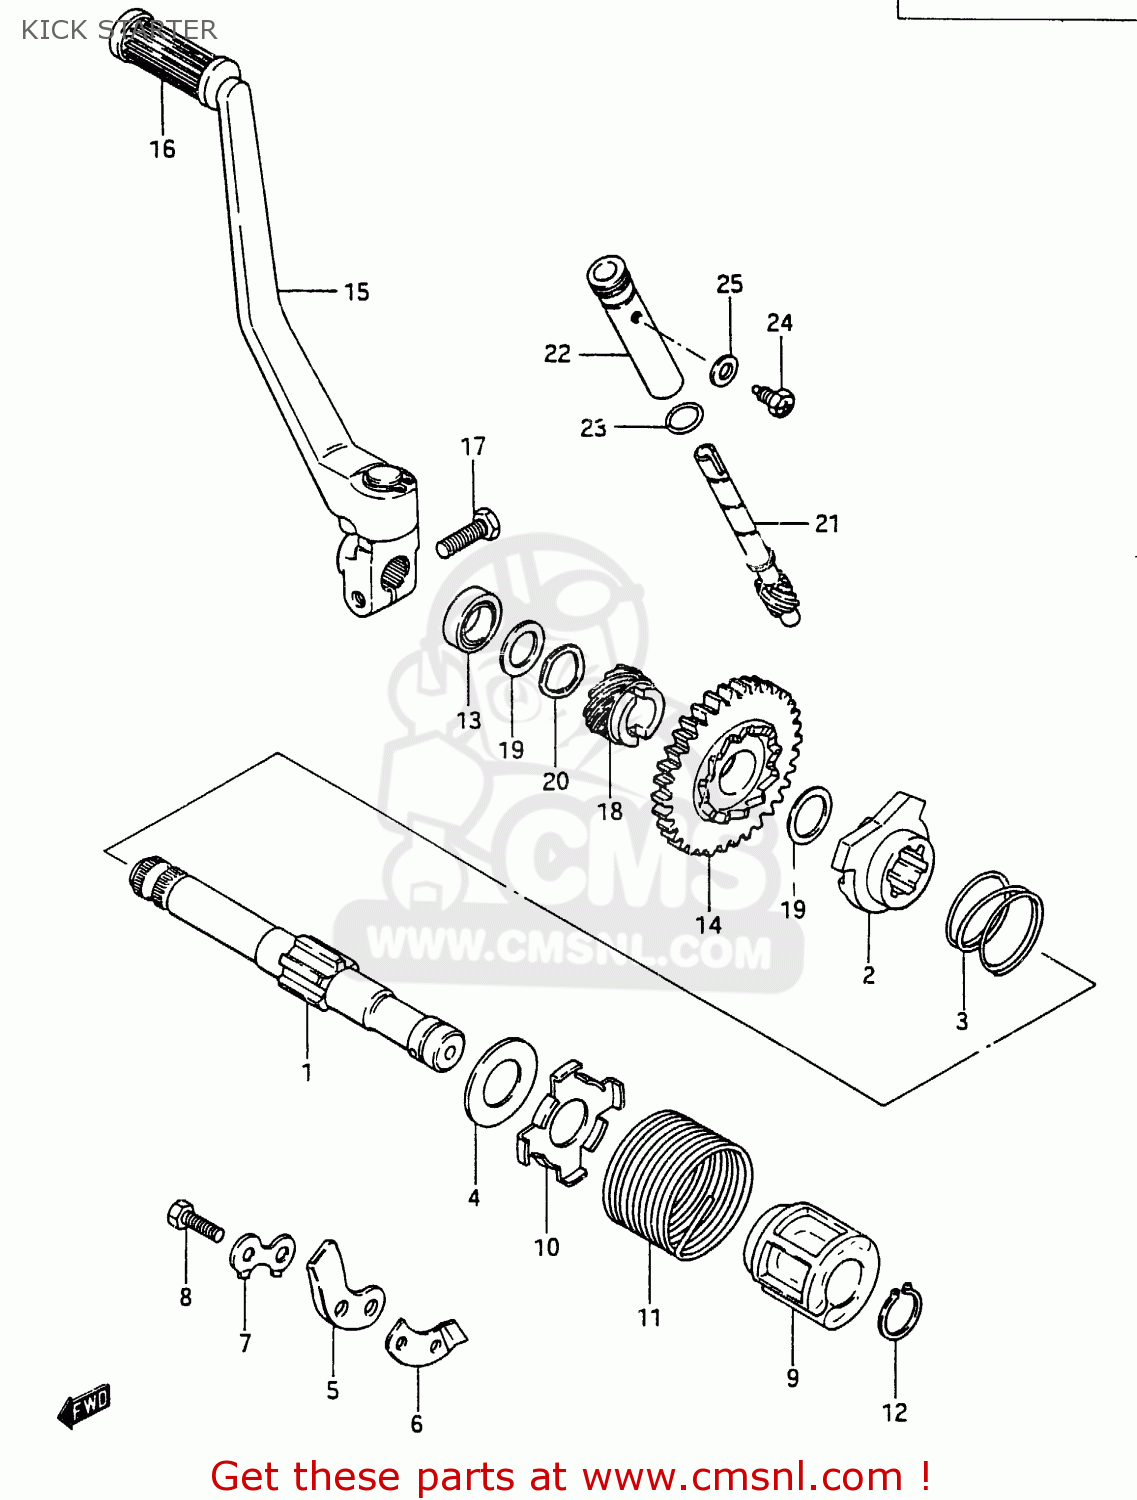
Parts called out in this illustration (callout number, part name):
1	SHAFT, KICK STARTER
2	STARTER, KICK
3	SPRING
4	WASHER
5	GUIDE, KICK STARTER
6	STOPPER,KICK STARTER
7	WASHER
8	BOLT
9	GUIDE,KICK SHAFT SPRING
10	HOLDER,KICK SHAFT SPRING
11	SPRING
12	CIRCLIP
13	SEAL,OIL(16X24X5)
14	GEAR, KICK STARTER DRIVE
15	LEVER ASSY
16	RUBBER,KICK STARTER PEDAL
17	BOLT 8X25
18	GEAR, TACHOMETER DRIVE (NT:13)
19	WASHER
20	WASHER
21	GEAR, TACHOMETER DRIVEN
22	SLEEVE,TACHOMETER DRIVE GEAR
23	O RING(D:1.3,ID:9.6)
24	BOLT
25	WASHER
